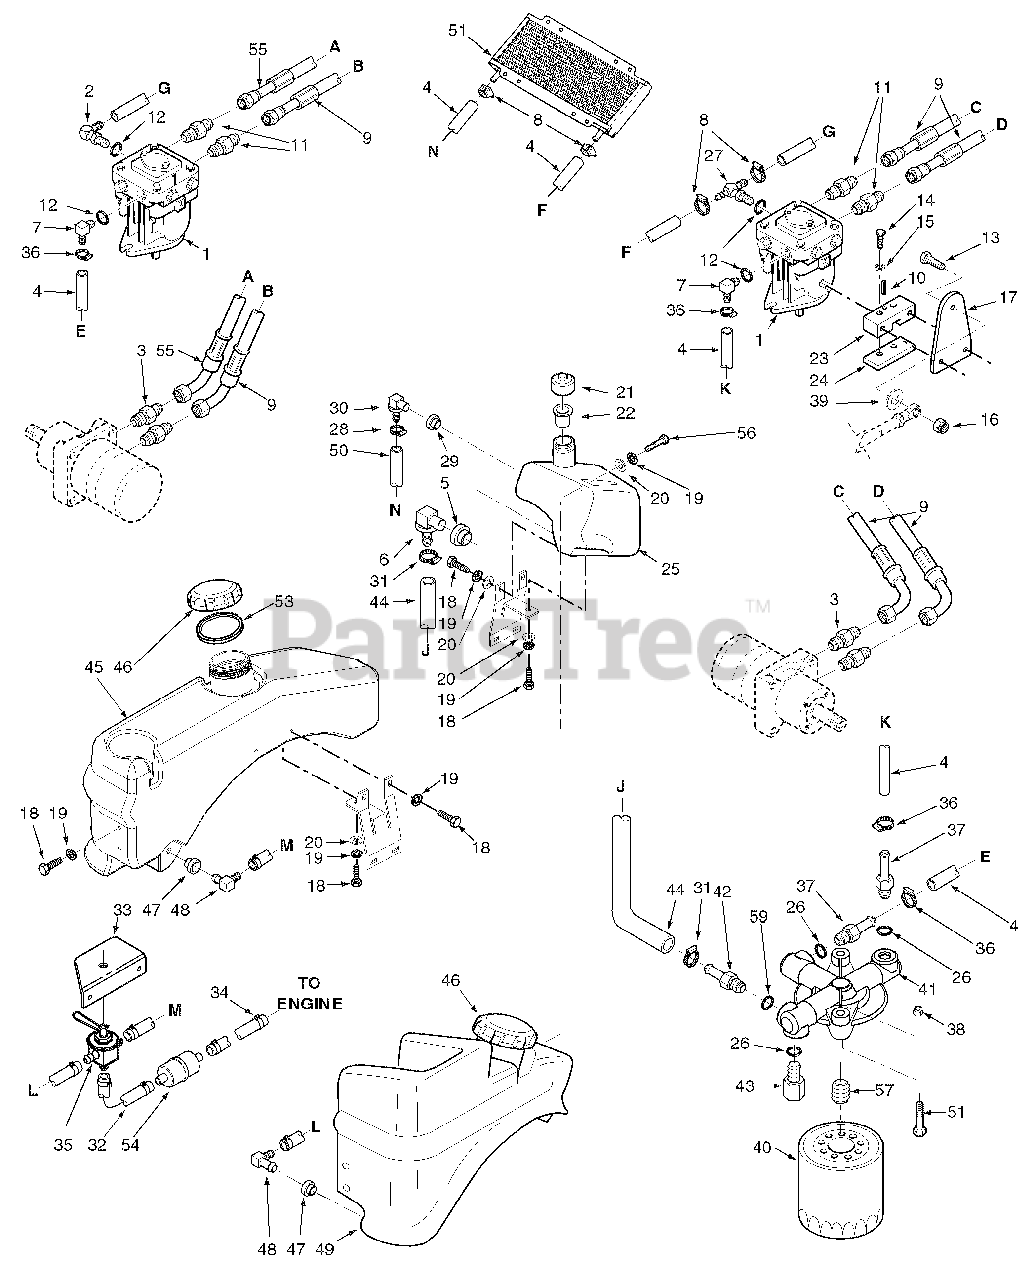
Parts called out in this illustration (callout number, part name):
1	Pump, BDP-10A-316
2	Elbow, 90 Degree 9/16 O-Ring x 3/8 Hose
3	Fitting, 1/2" JIC x 5/8 O-Ring
4	Hose, 3/8 Pushlock
5	Bushing
6	Fitting
7	Elbow, 90 Degree 9/16 O-Ring x 3/8 Hose
8	Hose Clamp, .69 Dia.
9	Hose Assembly
10	Roll Pin
11	Fitting, 1/2" JIC x 1/2" O-Ring
12	O-Ring
13	Bolt, Hex Head 3/8-16 x 1-1/2"
14	Bolt, Hex Head 1/4-20 x 1-1/4"
15	Lockwasher
16	Nut, Elastic Stop 3/8-16
17	Control Lever
18	Bolt, Hex Head 5/16-18 x 3/4"
19	Lockwasher, 5/16"
20	Flatwasher, 5/16-.375 x .875 x .083
21	Cap, Hydraulic Tank
22	Insert, Filler Neck
23	Control Block
24	Clamp Plate
25	Hydraulic Tank Assembly w/fittings
26	O-Ring
27	Tee Fitting, O-Ring to Barb
28	Clamp, .69 Max. / .25 Min. Dia.
29	Bushing
30	Elbow, 0.38 Hose
32	Fuel Hose, 1/4 ID Non-Perm.
33	Bracket Fuel Valve
34	Clamp, Fuel Hose 1/4 Hose ID
35	Valve, Fuel Shutoff
36	Clamp, .69 Max. / .25 Min. Dia.
37	Fitting, 9/16 O-Ring x 3/8 Hose
38	Nut, Serr. Flange 5/16-18
39	Flatwasher, 3/8-.391 x .938 x .105
40	Oil Filter
41	Filter Head Assembly
42	Fitting, 3/4 O-Ring x 3/8 Hose
43	Plug, 9/16-18 O-Ring
44	Hose, Filter Inlet
45	Fuel Tank RH
46	Cap, Fuel Tank
47	Tank Bushing
48	Elbow, 90 Degree
49	Fuel Tank LH
50	Hose, 3/8 Pushlock 15" Long
51	Cooler, Transmission
52	Screw, 1/4-20 x 2"
53	Gasket, Gas Tank Cap
54	Fuel Filter
55	Hose Assembly
56	Bolt, Hec Head 5/16-18 x 1-1/2"
57	Nipple, Oil Filter 1.0-12 UNF-2A x 1-1/4"
58	Bolt, Hex Head 5/16-18 x 2"
59	O-Ring, 3/4"
